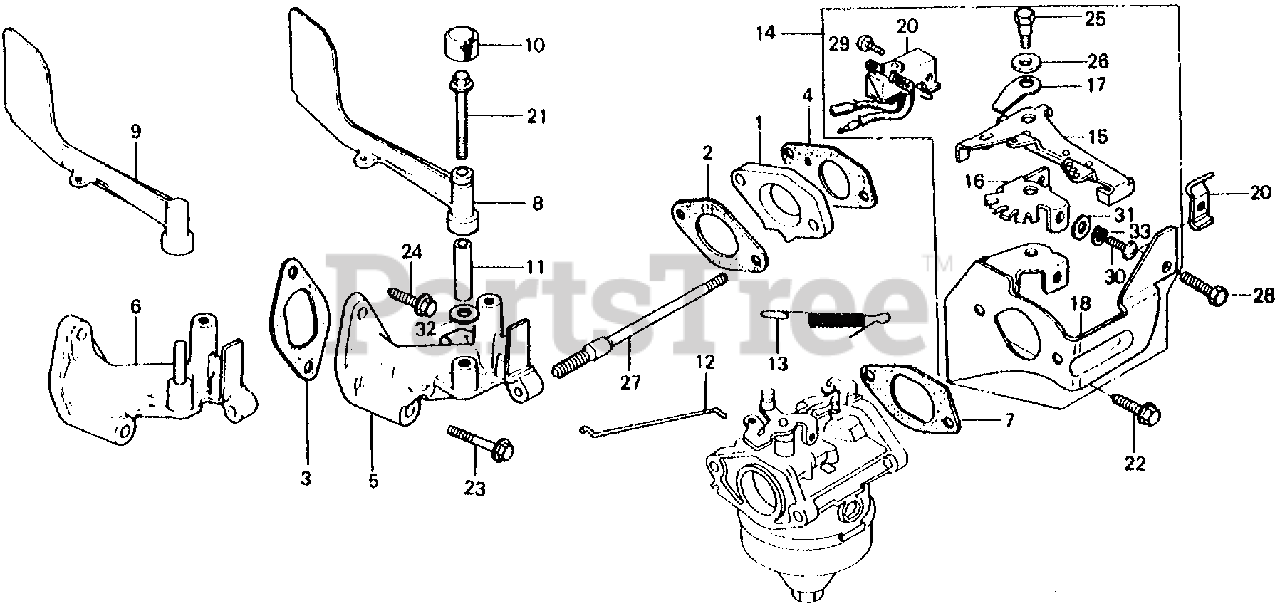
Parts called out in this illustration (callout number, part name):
1	INSULATOR, CARBURETOR
2	GASKET, INSULATOR (NOT AVAILABLE)
2	GASKET, INSULATOR
3	GASKET, MANIFOLD (NOT AVAILABLE)
3	GASKET, MANIFOLD
4	GASKET, CARBURETOR (NOT AVAILABLE)
4	GASKET, CARBURETOR
6	MANIFOLD, IN.
7	GASKET, AIR CLEANER (NOT AVAILABLE)
7	GASKET, AIR CLEANER
9	FLUTTER, GOVERNOR
12	ROD, GOVERNOR (NOT AVAILABLE)
13	SPRING, GOVERNOR
14	CONTROL ASSY.
15	LEVER, CONTROL
16	PLATE, LEVER SETTING
17	SPRING, LEVER SETTING (NOT AVAILABLE)
18	STAY, CLEANER CASE
19	HOLDER, WIRE
20	SWITCH ASSY., ENGINE STOP
22	BOLT, FLANGE (6X12) (CT200)
23	BOLT, FLANGE (6X50)
24	BOLT, FLANGE (6X20) (CT200)
25	BOLT, CONTROL LEVER
26	WASHER (7MM)
27	BOLT, STUD (6X141) (NOT AVAILABLE)
27	BOLT, STUD (6X141)
28	BOLT, HEX. (6X12)
29	SCREW, PAN (4X8)
30	SCREW, PAN (5X8)
31	WASHER, PLAIN (5MM)
33	WASHER, SPRING (5MM)
